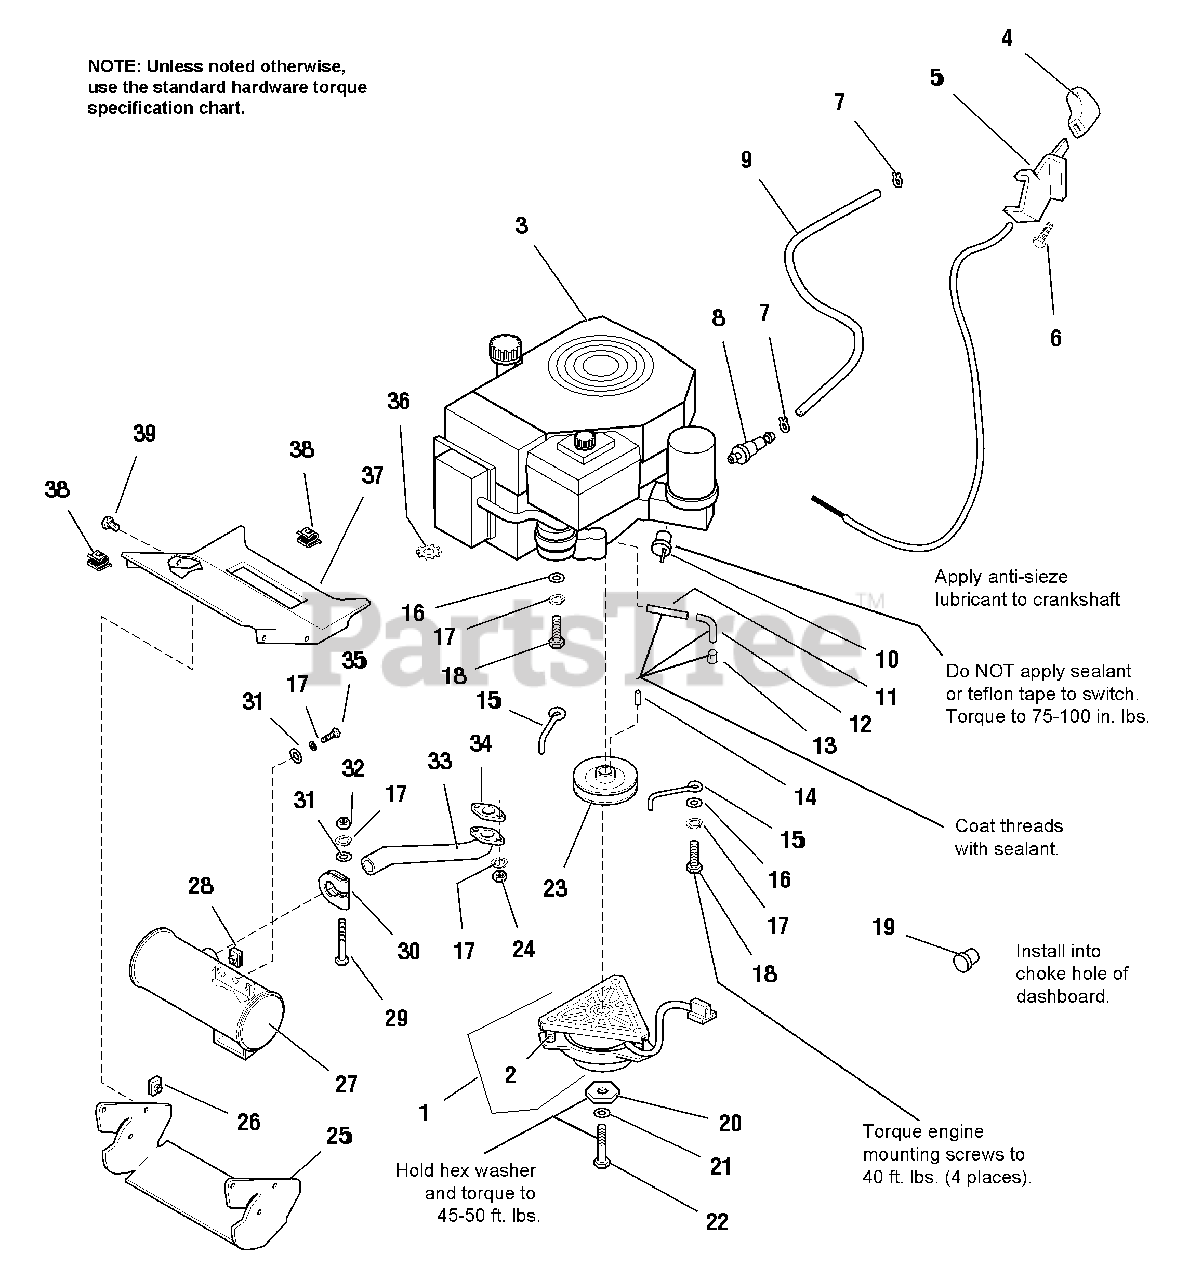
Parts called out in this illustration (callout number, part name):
1	ELECTRIC CLUTCH
2	SPRING & NUT KIT
3	ENGINE, 16HP Kohler Command
4	KNOB, Throttle
5	THROTTLE CONTROL ASSY.
6	CAPSCREW, Hex Washer Hd, Plastite, 1/4-20 x 1/2
7	CLAMP, Hose
8	FUEL FILTER
9	HOSE, Fuel, 45-1/2" Long
10	SWITCH, Oil Pressure
11	PIPE NIPPLE, 3/8 x 2
12	STREET ELBOW, 3/8 Pipe
14	KEY, Hi-Pro
16	WASHER, Flat, 5/16
17	LOCKWASHER, 5/16
18	CAPSCREW, Taptite, M8-1-1/4 x 30 mm
19	FASTENER, Panel
20	WASHER, Hex
21	LOCKWASHER, 7/16
22	CAPSCREW, 7/16-20 x 2-1/2
23	PULLEY ASSY
24	NUT, Exhaust
25	DUCT, Lower Muffler
26	PAL NUT, 1/4-20
27	MUFFLER ASSY.
28	PAL NUT, 5/16-18
29	CARRIAGE BOLT, 5/16-18 x 2-3/4
30	CLAMP, Muffler
31	WASHER, 5/16
32	NUT, Hex, 5/16-18
33	PIPE, Exhaust
34	GASKET, Exhaust
35	CAPSCREW, Hex Hd, 5/16-18 x 1
36	LOCKWASHER, External Tooth, 5/16
37	DUCT, Top, Muffler
38	CLIP
39	CAPSCREW, Hex Flange Hd, Whizlock, 1/4-20 x 5/8
